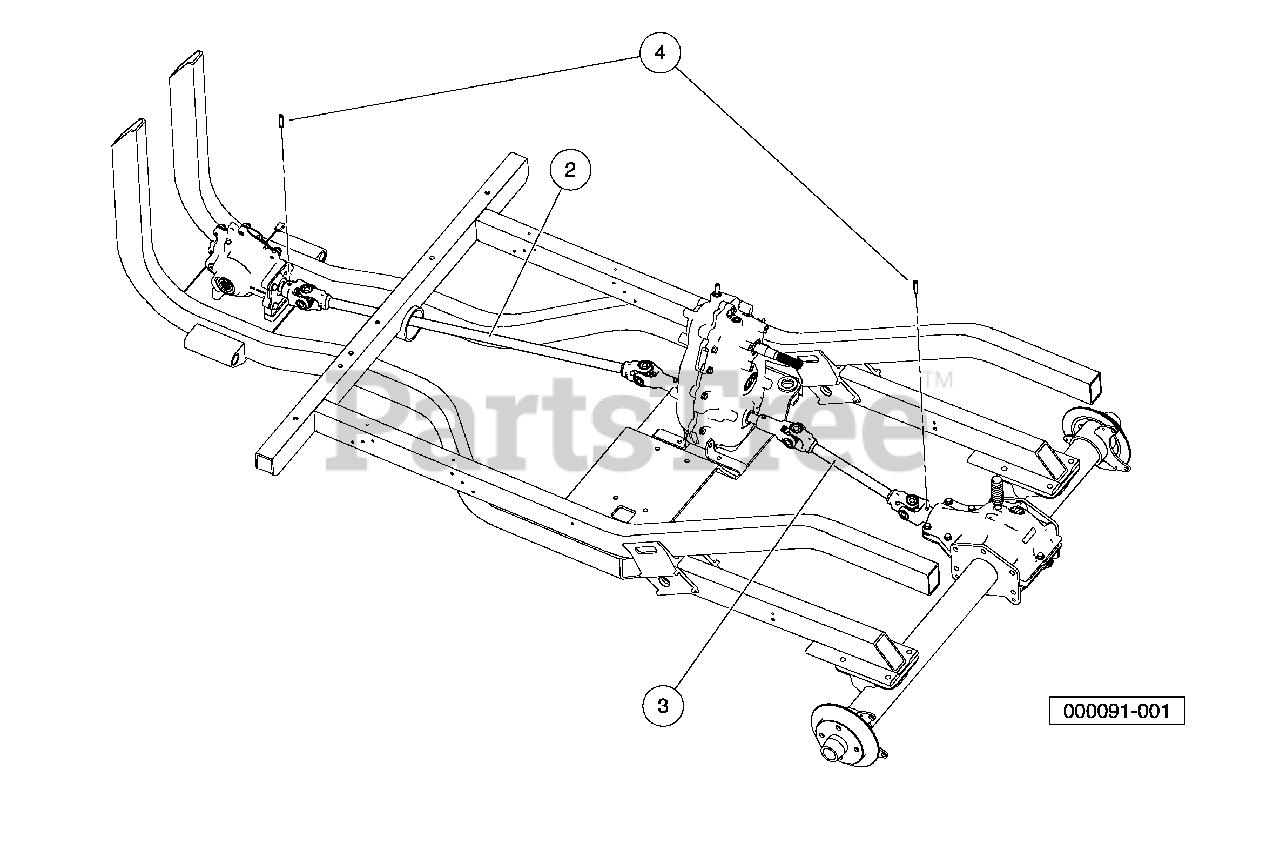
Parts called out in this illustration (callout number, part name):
1	Inst, Prop Shafts, Awd
2	Prop Shaft, Front
3	Prop Shaft, Rear
4	Pin, Spring, 5/16 X 1-1/2 Hd
